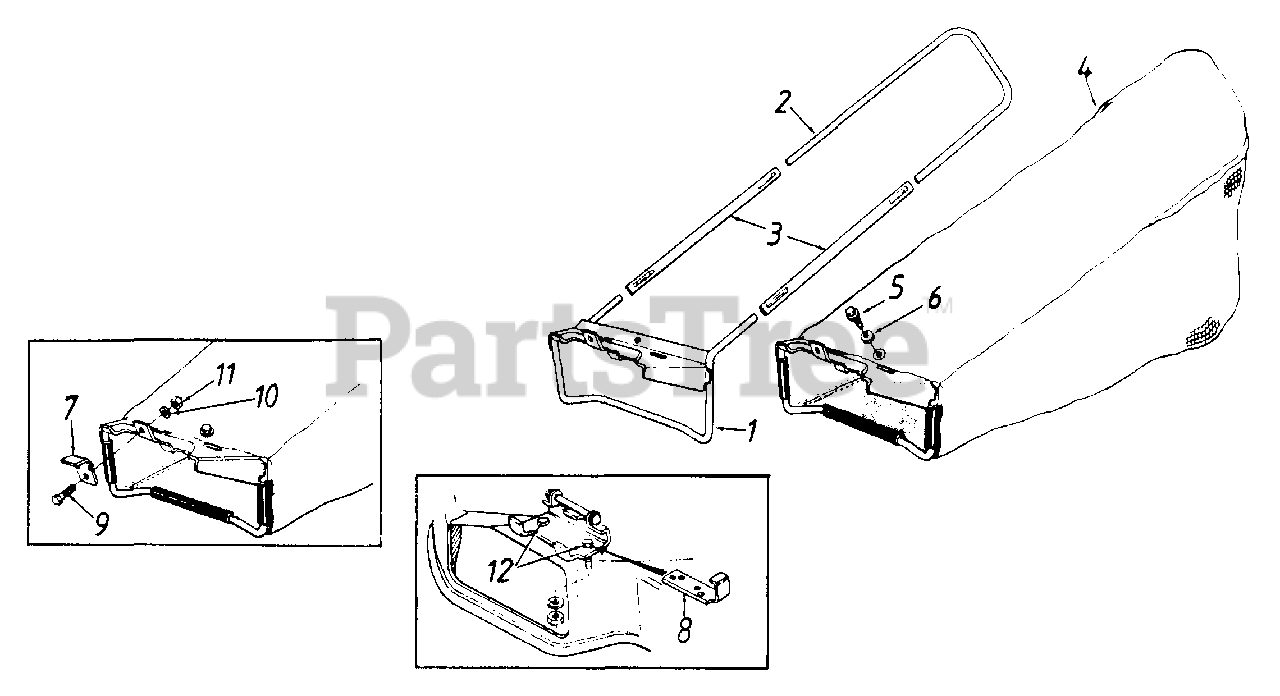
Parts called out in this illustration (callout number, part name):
4	Grass Bag
5	Hex Wash Hd. TT-Tap Scr. 1/4-20 x 5" Lg.
6	Bell-Wash. 1/4" I.D.
7	Deflector Stop
8	Support Plate
9	Hex Bolt 1/4-20 x .5" Lg.
10	L-Wash. 1/4" I.D.
11	Hex Nut 1/4-20 Thd.
12	Hex Bolt 1/4-20 x .62" Lg.
